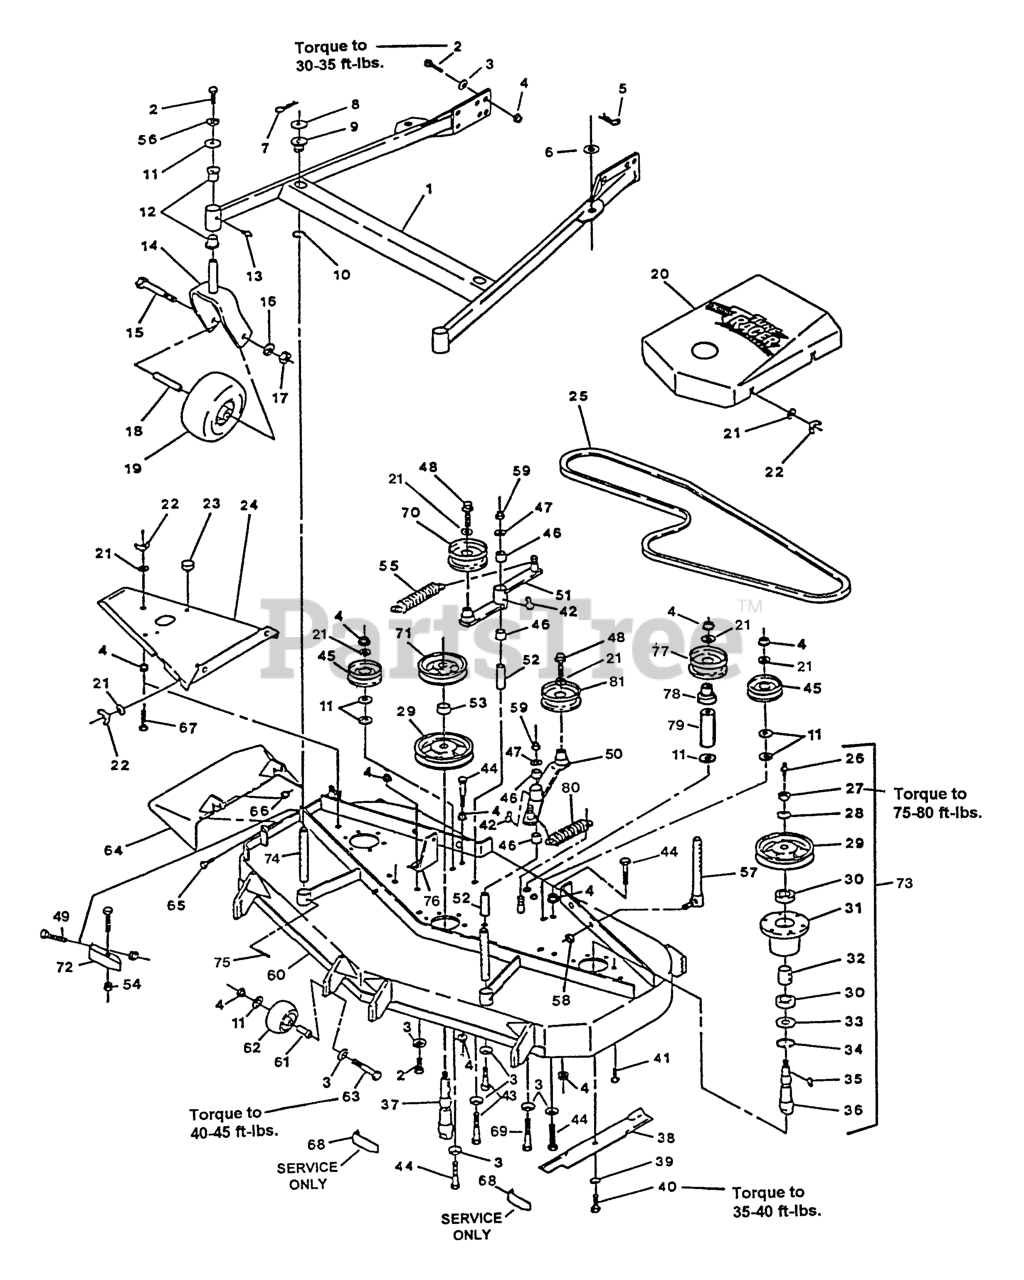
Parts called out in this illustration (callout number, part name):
1	SUPPORT ASSY-FMD60
5	PIN,HAIR COTTER
8	WASHER-FLAT
9	BUSHING-DECK
11	WASHER
12	BEARING-FLANGED
22	NUT-WING
24	WLD,DECK COVER
25	BELT-DRIVE, BLADE
28	WASHER-SPRING
29	SHEAVE,BLADE DRIVE
30	BEARING,HD SPINDLE
32	SPACER,BEARING
33	SEAL,MECHANICAL DUST
34	RING,SNAP WLDS N5000-244
36	SPINDLE-OUTER BLADE
37	SPINDLE-CENTER BLADE
39	WASHER-SPRING
41	SCRW,TPTTE HH
43	SCREW-HH
45	IDLER,PULLEY
46	SLEEVE-BEARING
50	Arm, Deck Drive Idler
51	Arm, Deck Idler
52	BUSHING-PIVOT, IDLER
53	SPACER-TUBE
55	SPRING-EXTENSION
61	BUSHING-ROLLER
62	ROLLER-SCALP, ANTI
70	IDLER,PULLEY
72	WLD,BAFFLE DISCHARGE
73	CH-52&60 OUTER CUTTR
74	ROD,DECK SUPPORT
76	BRACKET,SPRING ANCHOR
77	PULLEY-IDLER
78	BUSHING,IDLER
79	SPACER-FENDER
80	SPRING-EXTENSION
81	PULLEY-IDLER
